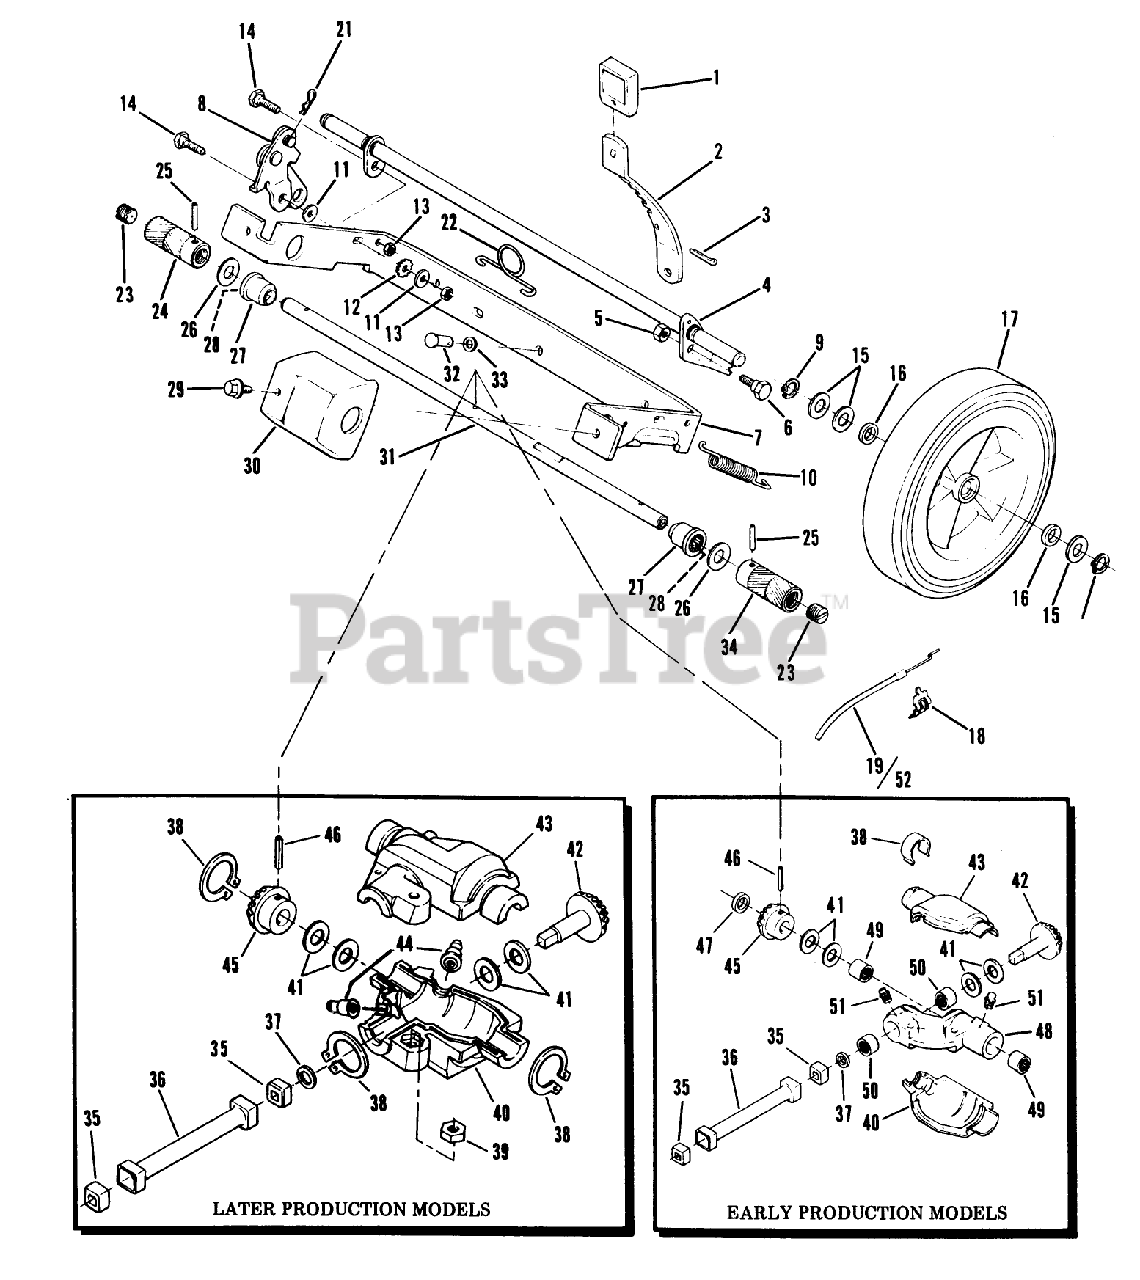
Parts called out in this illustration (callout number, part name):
5	LOCKNUT E
6	BOLT RB&W
7	BRK-21" AXLE
9	RET RING
11	WASHER S
13	STOP NUT
14	BOLT RB&W
20	RET RING
22	SPRING N.A.S
23	GREASE PLUG
28	BEARING AY F
31	DRIVE SHFT TAG AY
33	WASHER SPRING LAR
35	BUSHING
39	LOCKNUT E
41	THRUST WASHER
43	GEAR COVER UPPER
44	ZERK FITTING
46	ROLL PIN
50	NEEDLE BEARING
51	**FITTING LINCOLN
52	Cable-Interlock-Electric
